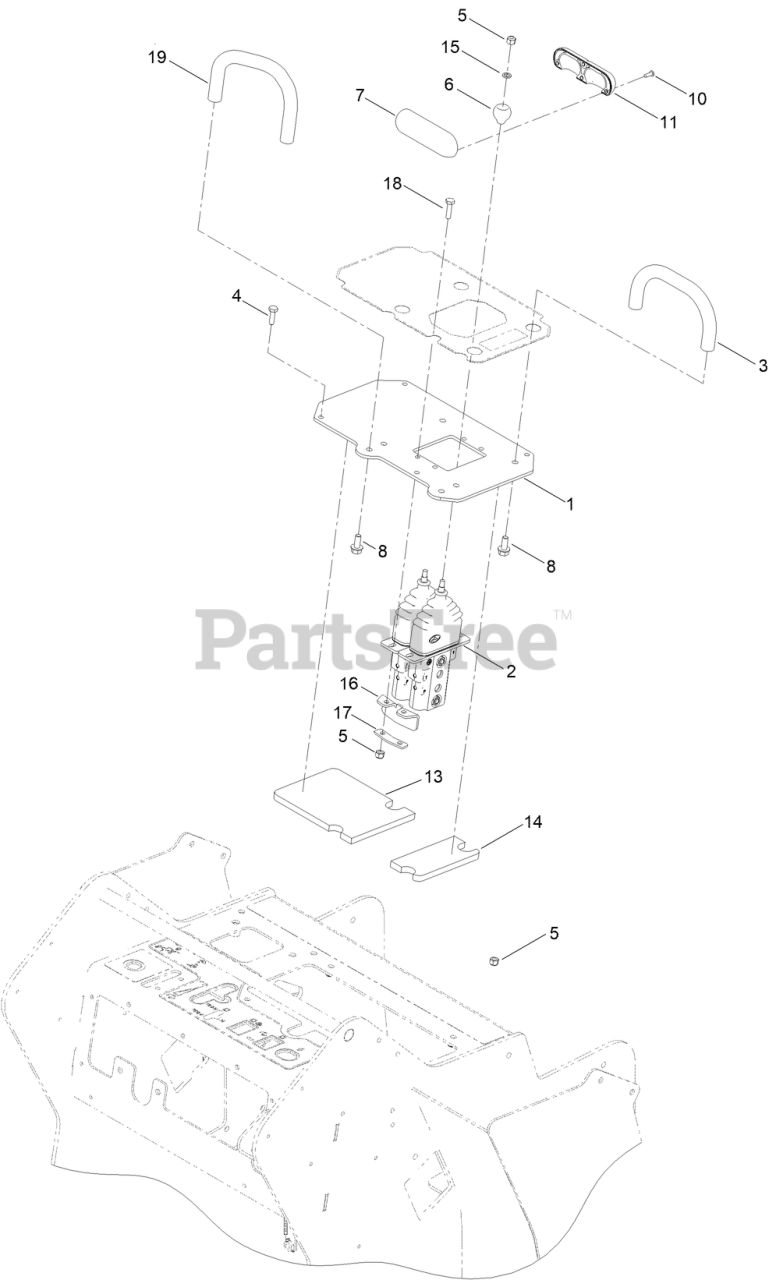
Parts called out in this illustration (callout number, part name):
1	PLATE-CONTROL
2	VALVE-CONTROL (TRACTION)
3	BAR-REFERENCE
4	SCREW-HH
5	NUT-LOCK, NI
6	BALL-TRACTION
7	HANDLE-CONTROL
8	SCREW-HHF
10	SCREW
11	HANDLE-TRACTION
13	FOAM-SHIELD, HEAT
14	FOAM-SHIELD, HEAT
15	SPACER-BEARING
16	COVER-RUBBER
17	PLATE-CLAMP
18	SCREW-HH
19	BAR-REFERENCE
